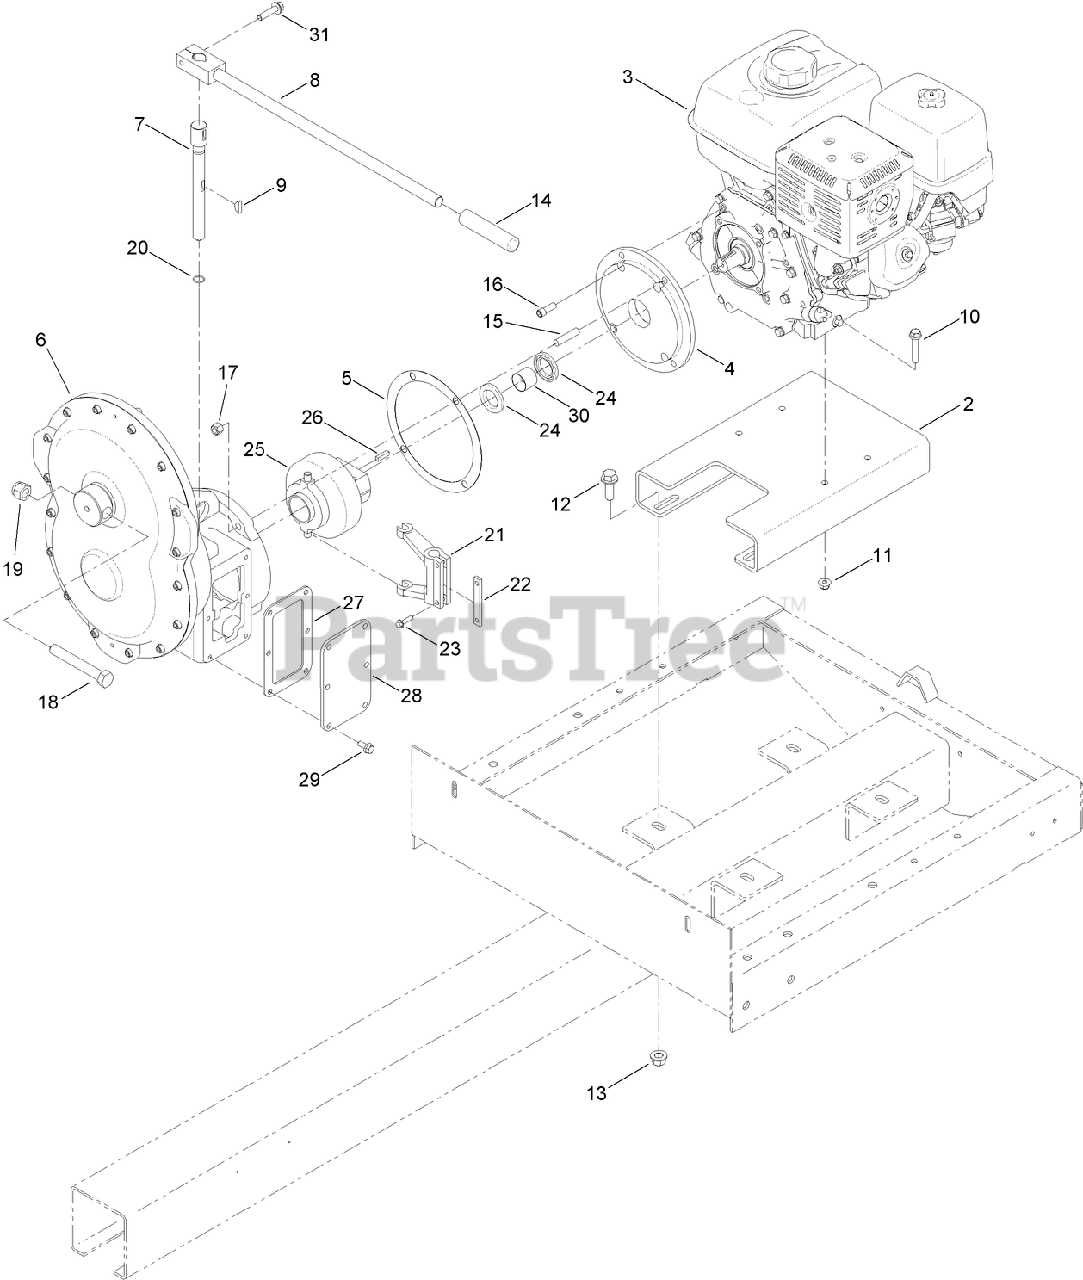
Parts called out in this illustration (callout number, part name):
2	BASE-MOTOR
3	ENGINE-HONDA, GX340
4	ADAPTOR-ENGINE
5	GASKET-ADAPTER, ENGINE
6	GEARCASE ASM
7	SHAFT-CLUTCH
8	HANDLE-CLUTCH
10	SCREW-HHF
11	NUT-HF, NI
12	SCREW-HHF
13	NUT-LOCK
14	GRIP-FLEX
16	SCREW-HSH
17	NUT-LOCK, NI
18	SCREW-HH
19	NUT-LOCK, NI
20	O-Ring
21	FORK-CLUTCH
22	SPACER-FORK, CLUTCH
23	SCREW-HHF
24	SEAL-SHAFT
25	CLUTCH-DISCONNECT, SLIP
27	GASKET-ACCESS, CLUTCH
28	COVER-CLUTCH ACCESS
29	SCREW-HHF
30	BUSHING-SHAFT
31	SCREW-HHF
